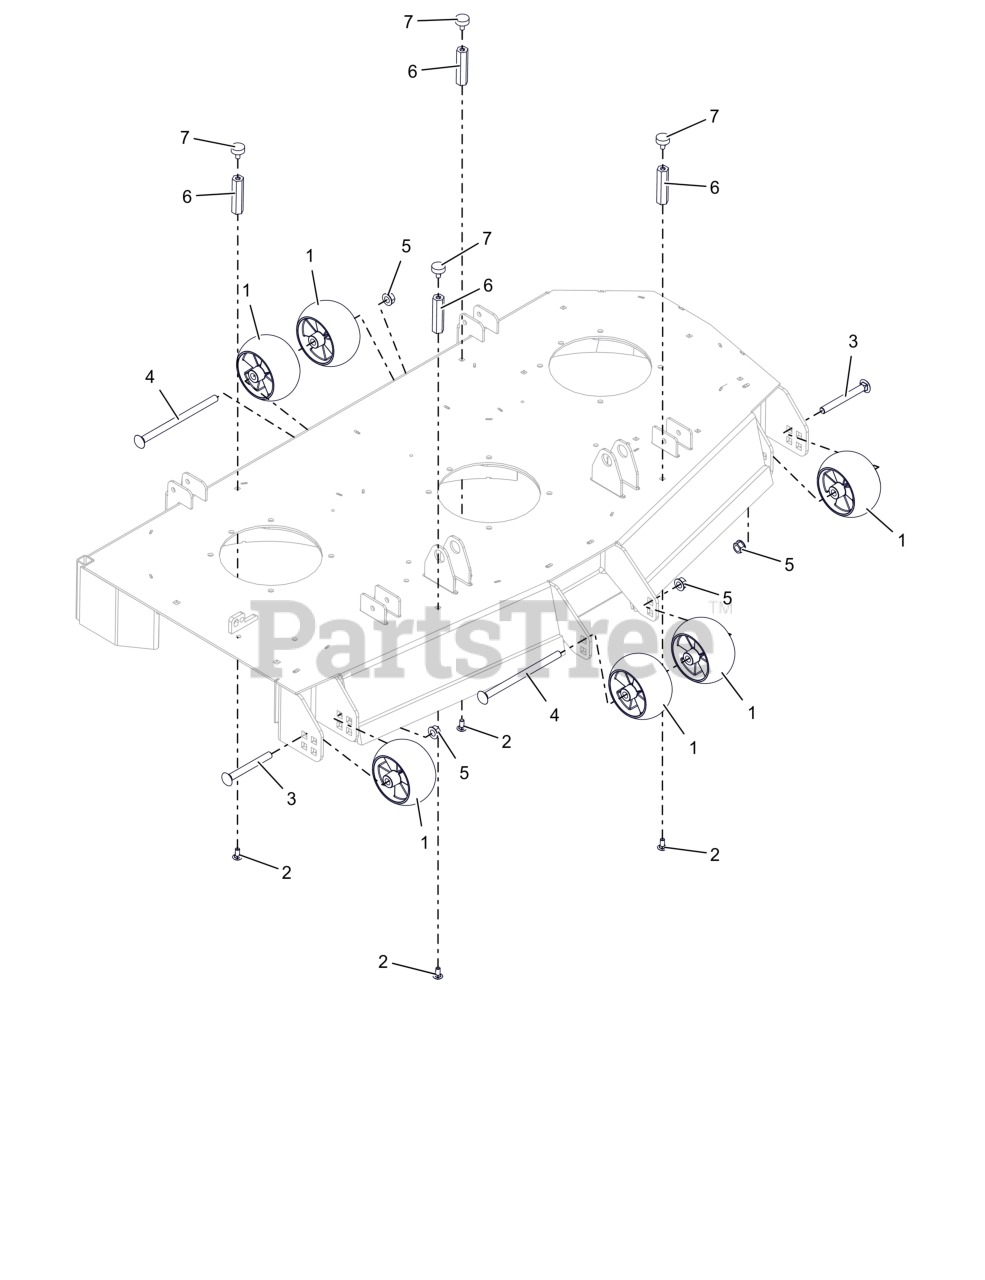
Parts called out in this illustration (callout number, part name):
1	WHEEL, ANTI SCALP - 5X3 CTR W/RIBS
2	BTL,RHSN .313-18 X 0.75 G5 ZCC LT
3	BLT,RHNS .50-13X4.50 G5 ZCC NS
4	BLT,RHSN .50-13X8.00 G5 ZCC NS
5	NUT-LK-CTR-FLG .500-13 GG ZCC
6	NUT, COUPLING .31-18 X 3.00
7	BUMPER, RUBBER
